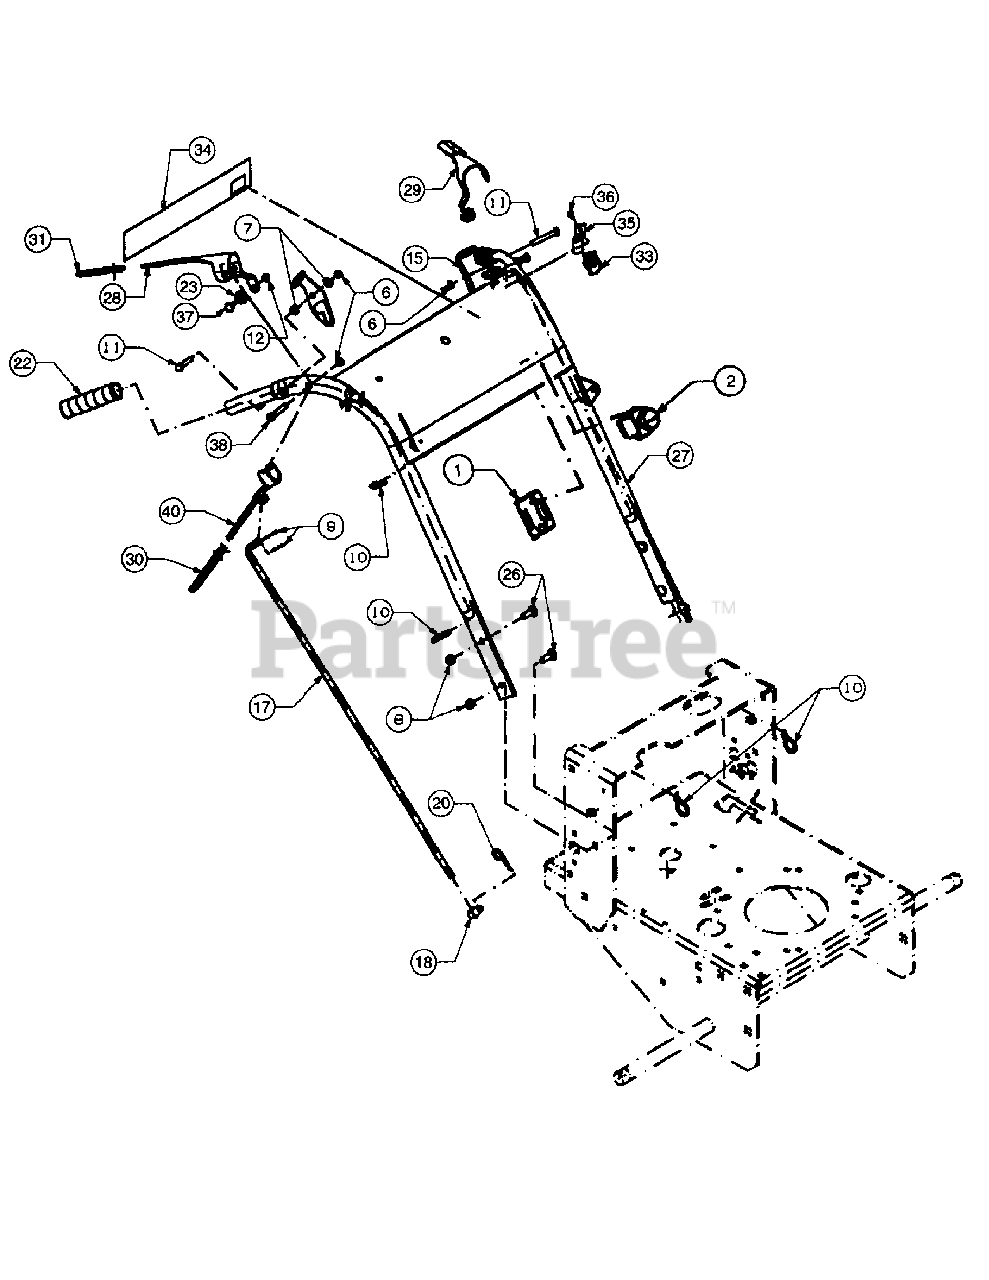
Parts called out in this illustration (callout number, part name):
1	PTO Switch Retainer Bracket
2	Electric PTO Switch
4	Grip, Neutral Latch, 1.25"
6	Nylock Nut, 5/16-18
7	Flat Washer, 5/16 Zinc
8	Lock Nut, Nylon Insert, 3/8-16
9	Cotter Pin, 3/32 x 3/4, Zinc
10	Cable Tie, 3/16 x .05 x 7.4
11	Hex Cap Screw, 5/16-18 x 2
12	Lock Nut, Nylon Insert
15	Neutral Latch, Left Hand
16	Neutral Latch, Right Hand
17	Steering Control Rod
18	Joint Swivel
20	Hair Pin 3/8-1/2
22	Plastic Handle Grip, Black, 4-5/8
23	Control Rod, Hydro Spacer
26	Carriage Bolt, 3/8-16 x 2
27	Handle Assembly Hydro
28	Operator Presence Control RH
29	Operator Presence Control LH
30	Control Sleeve, Black
31	Operator Control Sleeve, Yellow
32	Harness Assembly Adapter
33	Switch Mounting Snap
34	Handle Label, Rear, 5 Speed
35	Operator Presence Return Spring
36	Hex Index Washer Screw, 0.500
37	Shoulder Screw, .38 x .412, 1/4-28
38	Hex Cap Screw, 5/16-18, 2.00
40	Lever Assembly Control
